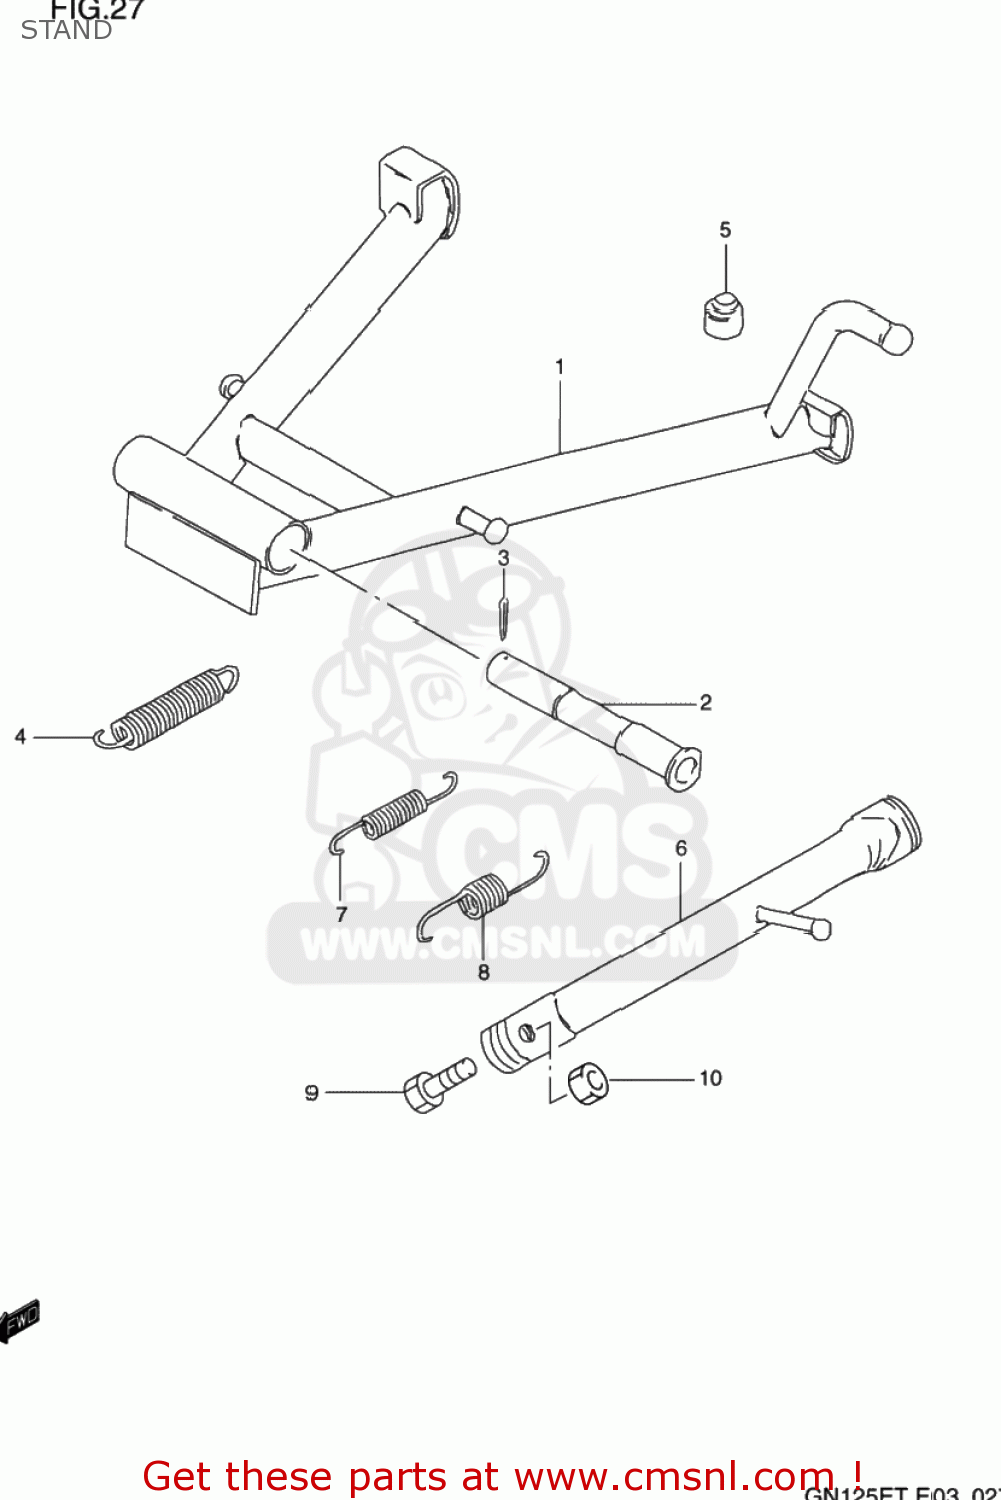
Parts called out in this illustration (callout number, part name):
1	STAND,CTR
2	SHAFT,CENTER STAND
3	COTTER PIN
4	SPRING
5	CUSHION
6	STAND,PROP
7	SPRING
8	SPRING
9	BOLT(10X30)
10	NUT
